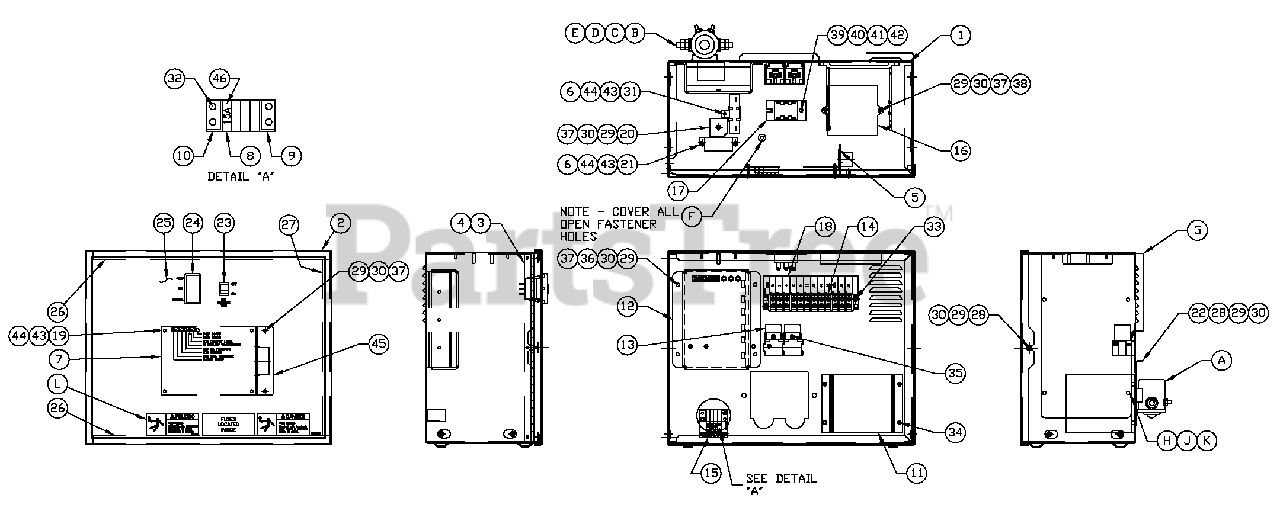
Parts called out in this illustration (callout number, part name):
1	ENCL HSB CONTROL PANEL
2	COVER CONTROL PANEL
3	HINGE CONTINUOUS H-PANEL
4	RIVET POP .125 X .275 SS
5	SCREW PPPH HI-LO #4-24 X 3/8
6	WASHER FLAT M3
7	ASSY PCB R-200 3600 RPM
8	HOLDER, FUSE WICKMANN 178.6150
9	ADPTR,RH SIDE WICKMAN 178.6191
10	ADPTR,LH SIDE WICKMAN 178.6192
11	ASSY PCB 2AMP 12V UL BATT CHGR
12	ASSY VOLTAGE REGULATOR 60HZ
13	RELAY, 12VDC C FORM W/DIODE
14	BLOCK TERM 20A 12 X 6 X 1100V
15	DECAL CPL CONTROL PANEL FUSES
16	ASSY PCB BOSCH GOV DRIVER
17	ASSY PCB SCR BRIDGE
18	DECAL CPL 3.9L TB1
19	SPACER 9.5H 3.2 ID
20	DIO BRIDGE 25A 600V
21	CIRCT BRK 7 X 1 ETA 46-500-P
22	PLATE,HARNESS CLAMP
23	SWITCH RKR DPST 125V SPD
24	SWITCH RKR DPDT ON-OFF-ON
25	DECAL, CONTROL HSB
26	SEAL COVER 3.18X12.7X382
27	SEAL COVER 3.18X12.7X283
28	SCREW HHPM M5-0.8 X 12
29	WASHER FLAT M5
30	WASHER LOCK M5
31	RES WW 15R 5% 25W QK CONN
32	SCREW PHTT M3.5-0.6 X 10
33	SCREW PHTT M3.5-0.6 X 16
34	SCREW PHTT M4-0.7 X 12 ZYC
35	SCREW PHTT M4-0.7 X 10 ZYC
36	SCREW PPHM M5-0.8 X 12 ZNC
37	NUT HEX M5-0.8 G8 CLEAR ZINC
38	SCREW PPHM M5-0.8 X 30 SS
39	SCREW PPHM M4-0.7 X 16
40	WASHER FLAT M4
41	WASHER LOCK #8-M4
42	NUT HEX M4-0.7 G8 YEL CHR
43	WASHER LOCK M3
44	NUT HEX M3-0.5 G8 YEL CHR
45	SUPPORT ANGLE PCB
46	FUSE ATO TYPE 15 AMP (BLUE)
47	HARN 3600RPM R200 CONTROL PNL
A	RELAY SOLENOID 12VDC PNL MNT
B	SCREW HHC 1/4-20 X 3/4 G5
C	WASHER FLAT 1/4-M6 ZINC
D	WASHER LOCK M6-1/4
E	NUT HEX 1/4-20 STEEL
F	SEAL WEATHER .45"DIA
G	COVER CONTROL PANEL SIDE
H	SCREW PPHM M5-0.8 X 12 ZNC
J	WASHER LOCK M5
K	WASHER FLAT M5
L	DANGER HIGH VOLTAGE (SPANISH)
